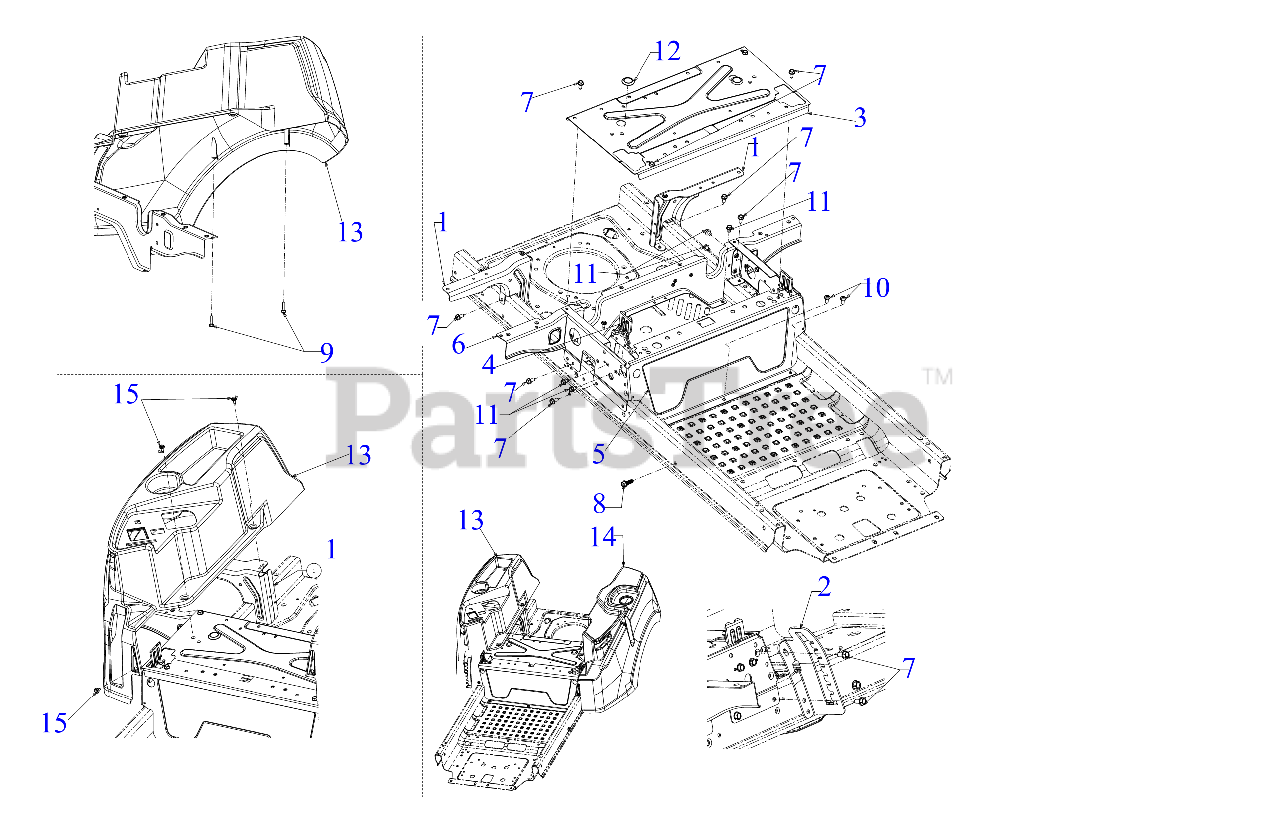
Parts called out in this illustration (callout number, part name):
2	HEIGHT INDEX BRACKET
7	SCREW 5/16-18 x .750
8	SCREW 3/8-16 x 1
9	SCREW 5/16-14 x 1
10	SCREW 5/16-18 X.75
11	SCREW 5/16-18 x .500
13	CONSOLE (RH)
14	CONSOLE (LH)
15	SHOULDER SCREW M6-1 .368 X.115
